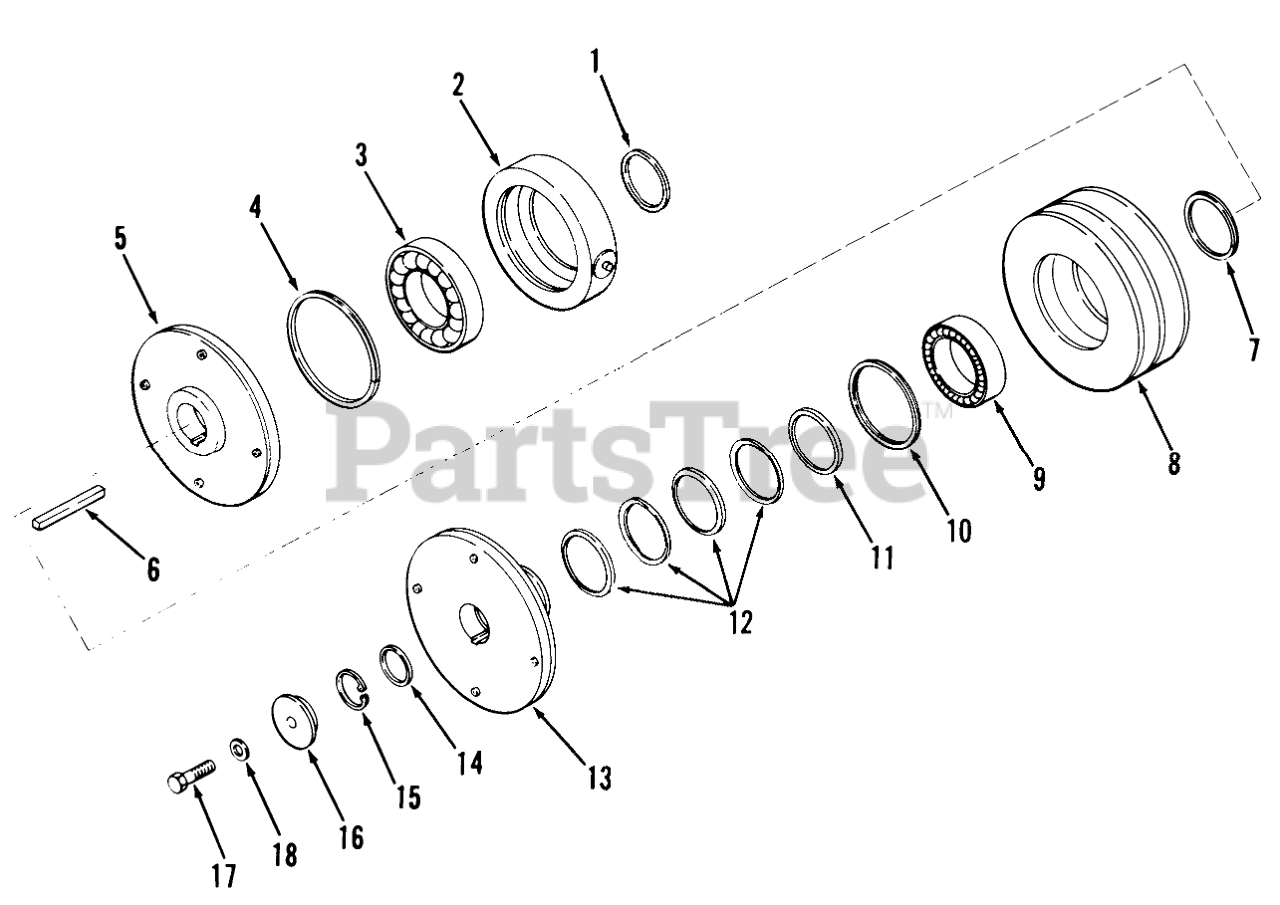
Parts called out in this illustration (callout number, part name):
1	RING EXTERNAL
2	ASSY COLLAR
3	BEARING
4	RING INTERNAL
5	ASSY CLUTCH PLATE
7	RING EXTERNAL
8	PULLEY CLUTCH
9	BEARING
10	RING INTERNAL
11	WASHER
12	SPRING WASHER
13	Assy-Outer Clutch
14	WASHER
15	INTERNAL RING
16	END CAP
18	LOCKWASHER
